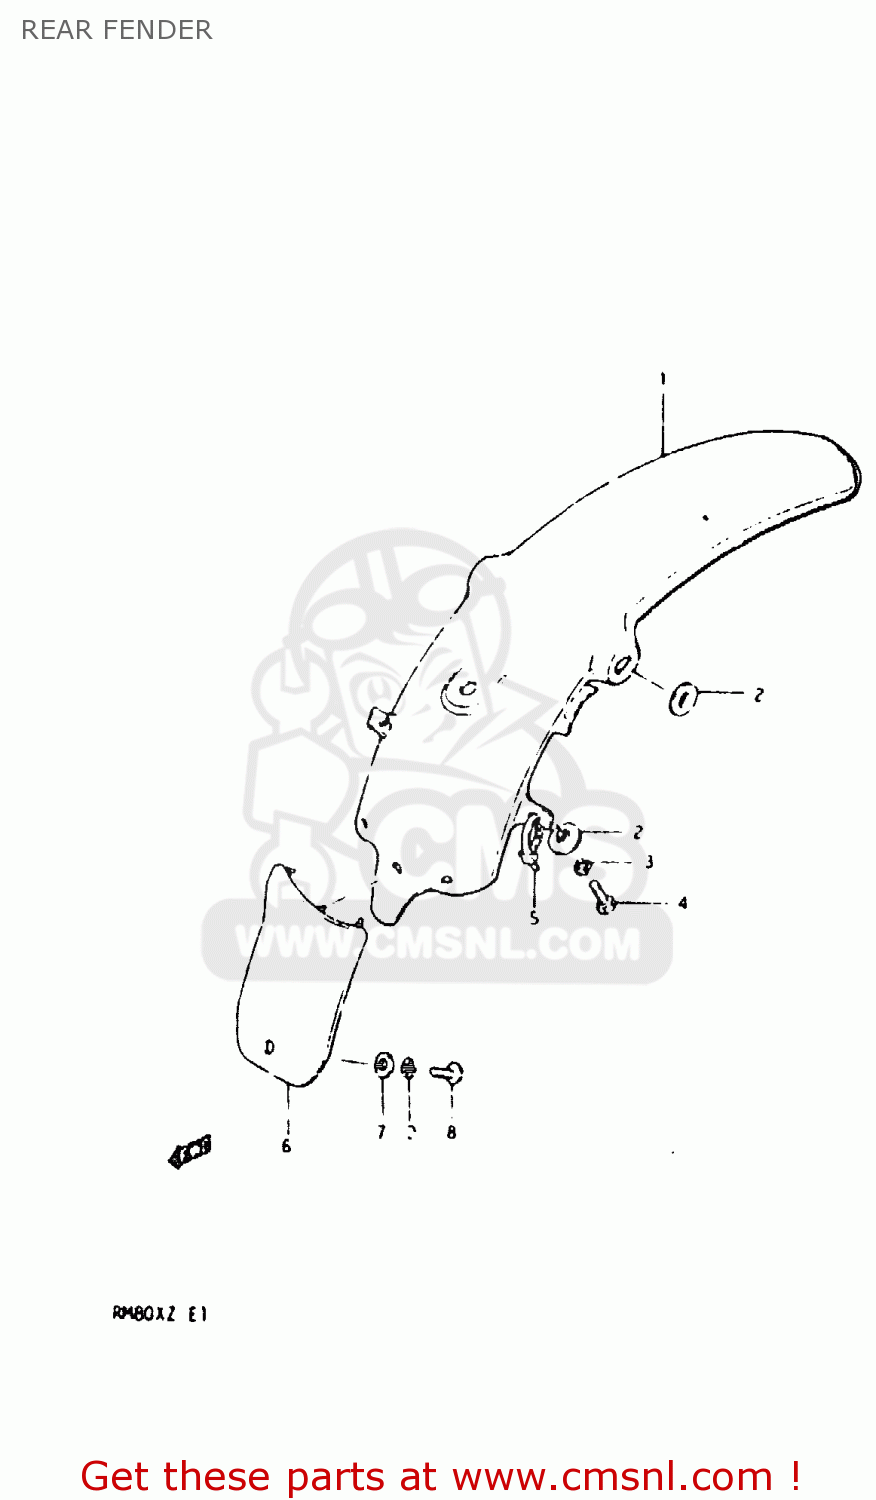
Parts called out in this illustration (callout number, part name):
1	FENDER,REAR
2	WASHER
3	LOCK WASHER
4	BOLT, UPPER
5	CLAMP
6	MUD GUARD,REAR FENDER
7	WASHER
8	BOLT
9	LOCK WASHER
